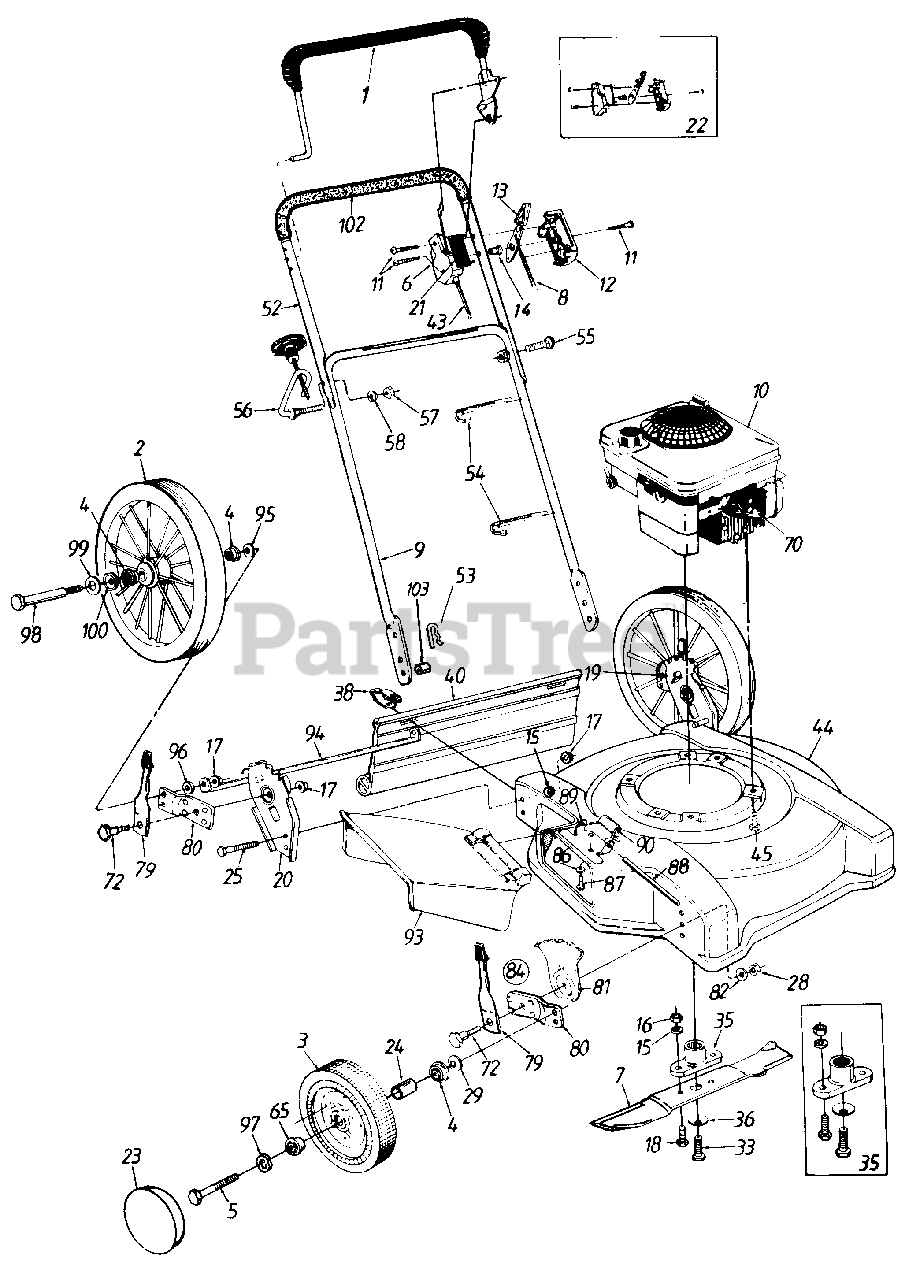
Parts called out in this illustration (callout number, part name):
1	Control Handle
2	16" Wheel Ass'y. Comp. (Steel)
3	Front Wheel Ass'y. Comp.
4	Bearing 1/2" I.D.
5	Front Axle Bolt
6	Clutch Panel Half
7	22" Blade
8	Throttle Cable-53"
9	Lower Handle
10	Engine
11	Truss Mach. Scr. #12 x 1.5" Lg.
12	Control Panel Half
13	Throttle Control Lever
14	Control Disc Pin
15	L-Wash. 3/8" I.D.*
16	Hex Nut 3/8-24 Thd.
17	Hex Nut 3/8-24 Thd.
18	Hex Bolt 3/8-24 x 1.0" Lg.
19	Wheel Brkt. Ass'y.-L.H.
20	Wheel Brkt. Ass'y.-R.H.
21	Control Label-Throttle
22	Kit-Control Housing Comp.
25	Rib Neck Bolt 3/8-24 x .62" Lg.
28	Hex Nut 3/8-16 Thd.*
29	Bell-Wash. .400" I.D. x .88"
33	Hex Bolt 7/16-20 x 1.5" Lg.
35	Blade Adapter Kit (Splined)
36	Bell-Wash. .46" I.D.
38	Hinge Clip
40	Rear Flap Ass'y.
43	Control Cable-39"
44	638/N 22" Deck Ass'y.
45	Hex Wash. Hd. TT-Tap Scr. 3/8-16 x 1.00" Lg.
52	Upper Handle
53	Intern. Cot. Pin 5/16" Dia.
54	Cable Tie
55	Curved Carriage Bolt 5/16-18 x 1.38" Lg.
56	Rope Guide Bolt
57	Hex Nut 5/16-18 Thd.
58	L-Wash. 5/16" I.D.*
65	Ball Bearing 3/8" I.D.
70	Spark Plug Boot
72	Shoulder Bolt .50" Dia. I
79	Spring Lever Ass'y. w/Knob
81	Height Adj. Plate
82	Bell-Wash. .39" I.D. x 1.38"
84	Front Height Adj. Ass'y. Comp.-R . H .
86	Bell-Wash. .285" I.D. x .75" O.D.
87	Hex Wash. Hd. Tap Scr. l/4-20 x 5" Lg.
88	Hinge Pin
89	Adapter Plate
90	Torsion Spring
93	Chute Deflector Ass'y. Comr
94	Stabilizer Tube
95	Bell-Wash. .39" I.D. x 1.13"
96	Spacer .503" I.D. x .75
97	Wave Washer .53" I.D.
98	Rear Axle Bolt
99	Fl-Wash. .51" I.D. x 1.0"
100	Spr. Wash. .5" I.D. x 1.0"
102	Foam Grip
103	Spacer
